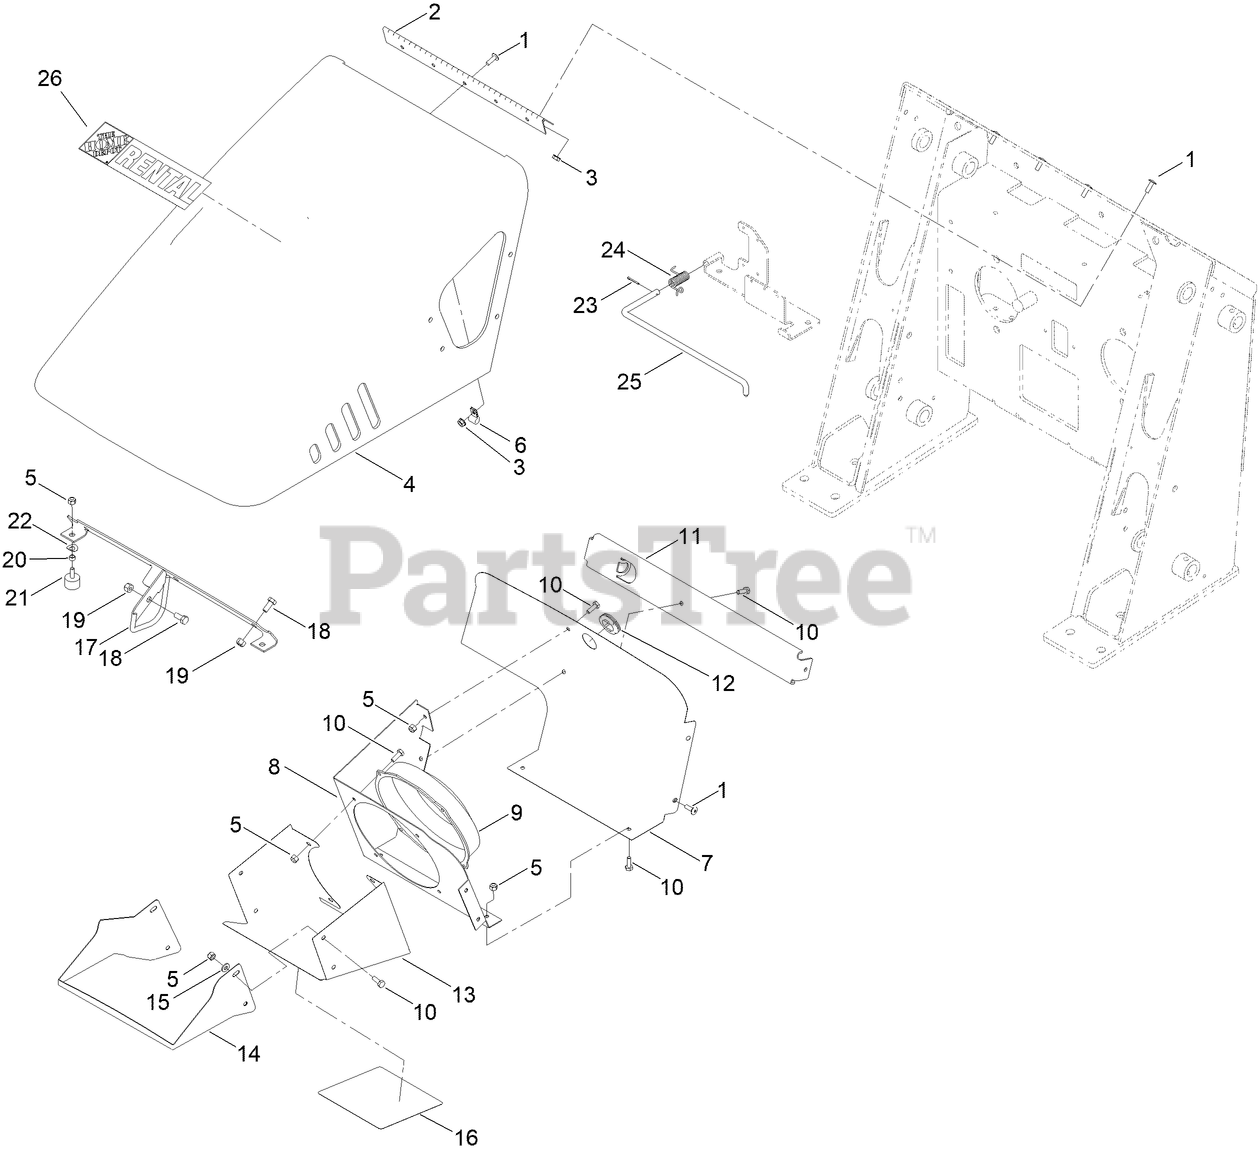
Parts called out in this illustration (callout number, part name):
1	SCREW-HEAD, TRUSS
2	HINGE-HOOD
3	NUT-HF
5	NUT-LOCK, NI
6	CLAMP
7	BRACKET-FAN, BACK
8	BRACKET-FAN, BACK
10	SCREW-HH
11	BRACKET-SUPPORT, HOOD
12	GROMMET
13	SHROUD-FAN
14	SHROUD-FAN, FRONT
15	WASHER-FLAT
16	DECAL-SERVICE TX427 DE
16	DECAL-SERVICE TX427 ES
16	DECAL-SERVICE TX427 FR
16	DECAL-SERVICE TX427 IT
16	DECAL-SERVICE TX427 NE
16	DECAL-SERVICE TX427 PL
16	DECAL-SERVICE TX427 RU
16	DECAL-SERVICE TX427 SK
16	DECAL-SERVICE, TX 427
17	LATCH-ROD
18	SCREW-HH
19	NUT-LOCK, NI
20	SPACER
21	BUMPER
22	WASHER-SPRING
23	PIN-COTTER
24	SPRING-TORSION
25	ROD-SUPPORT, HOOD
26	DECAL - HDHLW3X10
